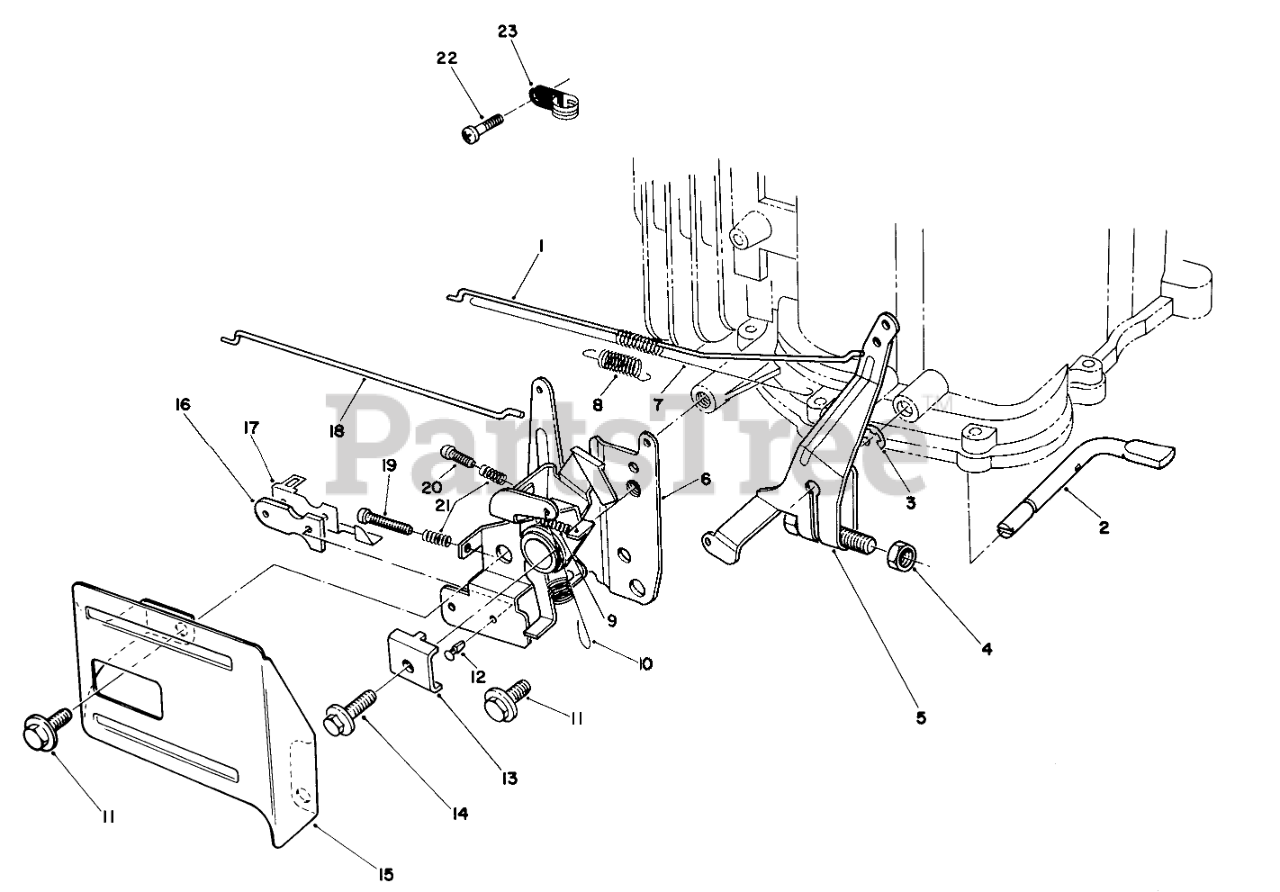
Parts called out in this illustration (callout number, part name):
1	Rod-Carburetor
2	SHAFT
3	E-RING
4	Nut
5	ARM ASM
6	THROTTLE
7	SPRING
8	SPRING
9	SPRING
10	SPRING
12	RIVET
13	CLAMP-CABLE
15	THROTTLE GUARD
16	INSULATOR-KILL SWITCH
17	TERMINAL-KILL SWITCH
18	Rod-Choke
19	SCREW
20	SCREW
21	SPRING
22	SCREW
23	Clamp
